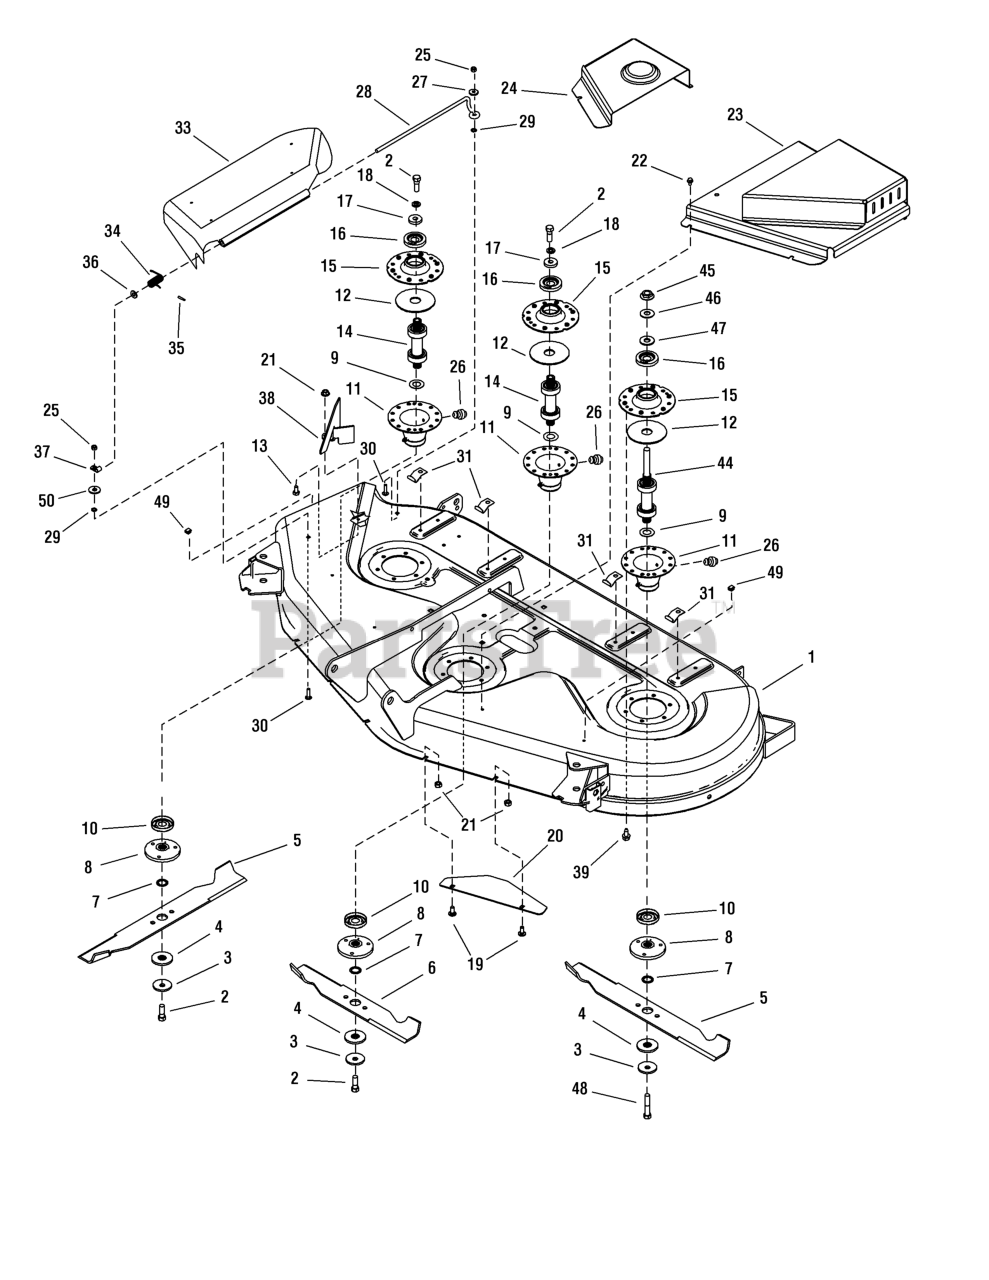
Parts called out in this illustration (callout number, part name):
1	HOUSING ASSEMBLY, 54" Mower
2	CAPSCREW, Hex Head 7/16-14 x 1-1/4 G8
3	WASHER, Spring
4	WASHER, Splined
5	BLADE, Mower 20.56
6	BLADE, Mower 16.00
7	RETAINING RING, Self Locking
8	ADAPTER, Blade
9	WASHER, Shim
10	SHIELD, Bearing
11	HOUSING & FITTING ASSEMBLY, Lower
12	GASKET, Foam
13	CAPSCREW, Hex Head 5/16-18 x 5/8 G5
14	ARBOR SHAFT & BEARINGS ASSEMBLY
15	HOUSING, Arbor Top
16	SHIELD, Bearing, Mower Arbor, Upper
17	WASHER
18	LOCKWASHER, Spring
19	BOLT, Carriage, 5/16-18 x 3/4 G5
20	BAFFLE, Front
21	NUT, Hex KEPS 5/16-18 Conical Washer
22	SCREW, Hex Washer Head Taptite 1/4-20 x 3/8
23	COVER ASSEMBLY, Upper
24	COVER, Arbor R.H. 54"
25	NUT, Hex Lock ESNA Light 1/4-20
26	FITTING, Lube, 1/4 Drive
27	WASHER, 1/4
28	ROD, Deflector
29	NUT, Push
30	CARRIAGE BOLT, 1/4-20 x 1 G5
31	CLIP, Spring
33	DEFLECTOR
34	SPRING, Torsion, Chute
35	CAP, Spring End
36	WASHER, 5/16
37	CLAMP, Wire, 5/16 Diameter
38	BAFFLE, Discharge
39	CAPSCREW, Hex Washer Head Taptite 5/16-18 x 3/4
44	ARBOR SHAFT & BEARINGS ASSEMBLY, 40"
45	NUT, Hex Flange 9/16-18
46	WASHER, Bellville .56ID x 1.34 OD x .05T
47	WASHER, 1/2
48	CAPSCREW, Hex Head 7/16-14 x 2-1/4 G8
49	PLUG, Hole
50	WASHER, 1/4
